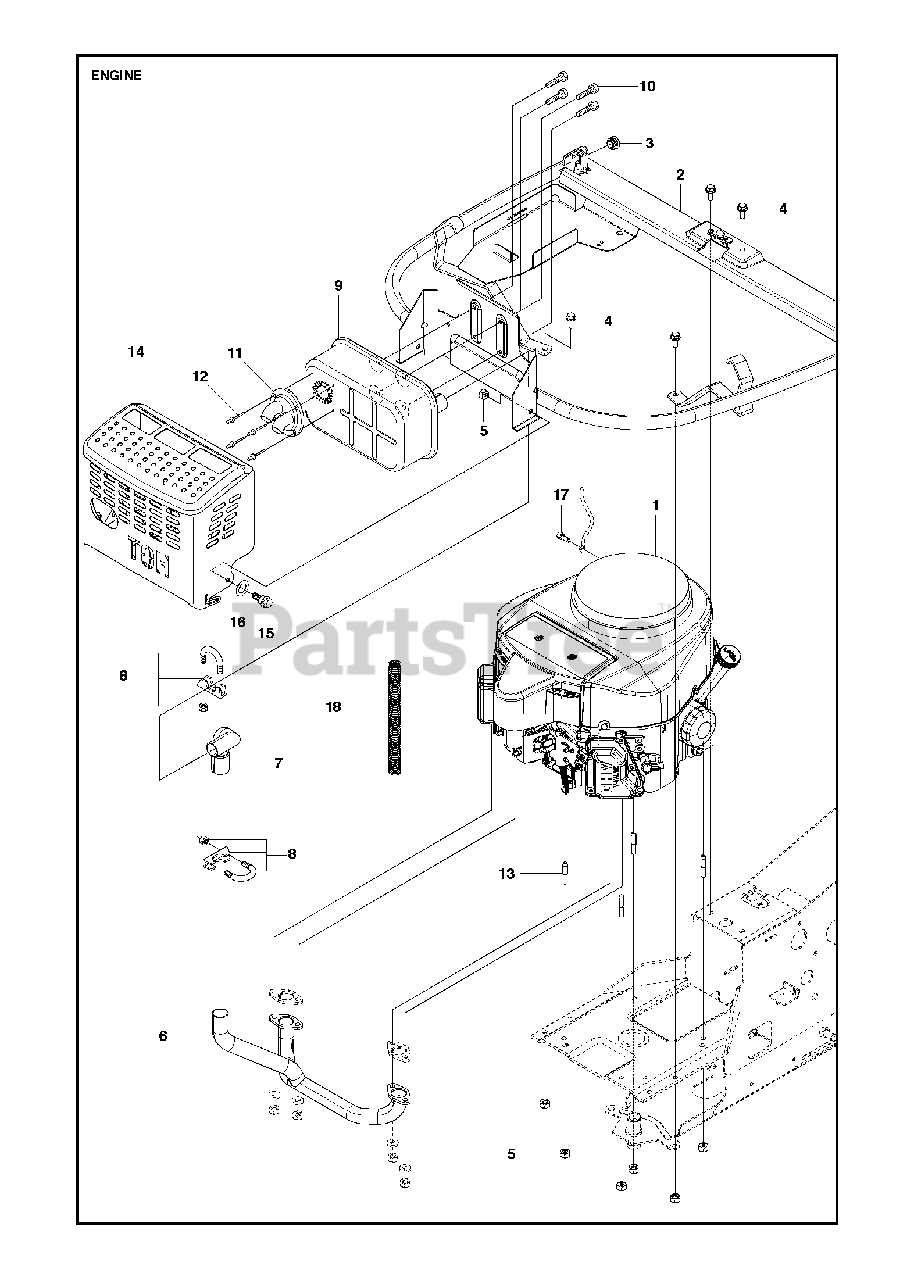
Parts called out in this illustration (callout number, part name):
5	LOCKNUT M8
9	MUFFLER
16	SPRINGWASHER
